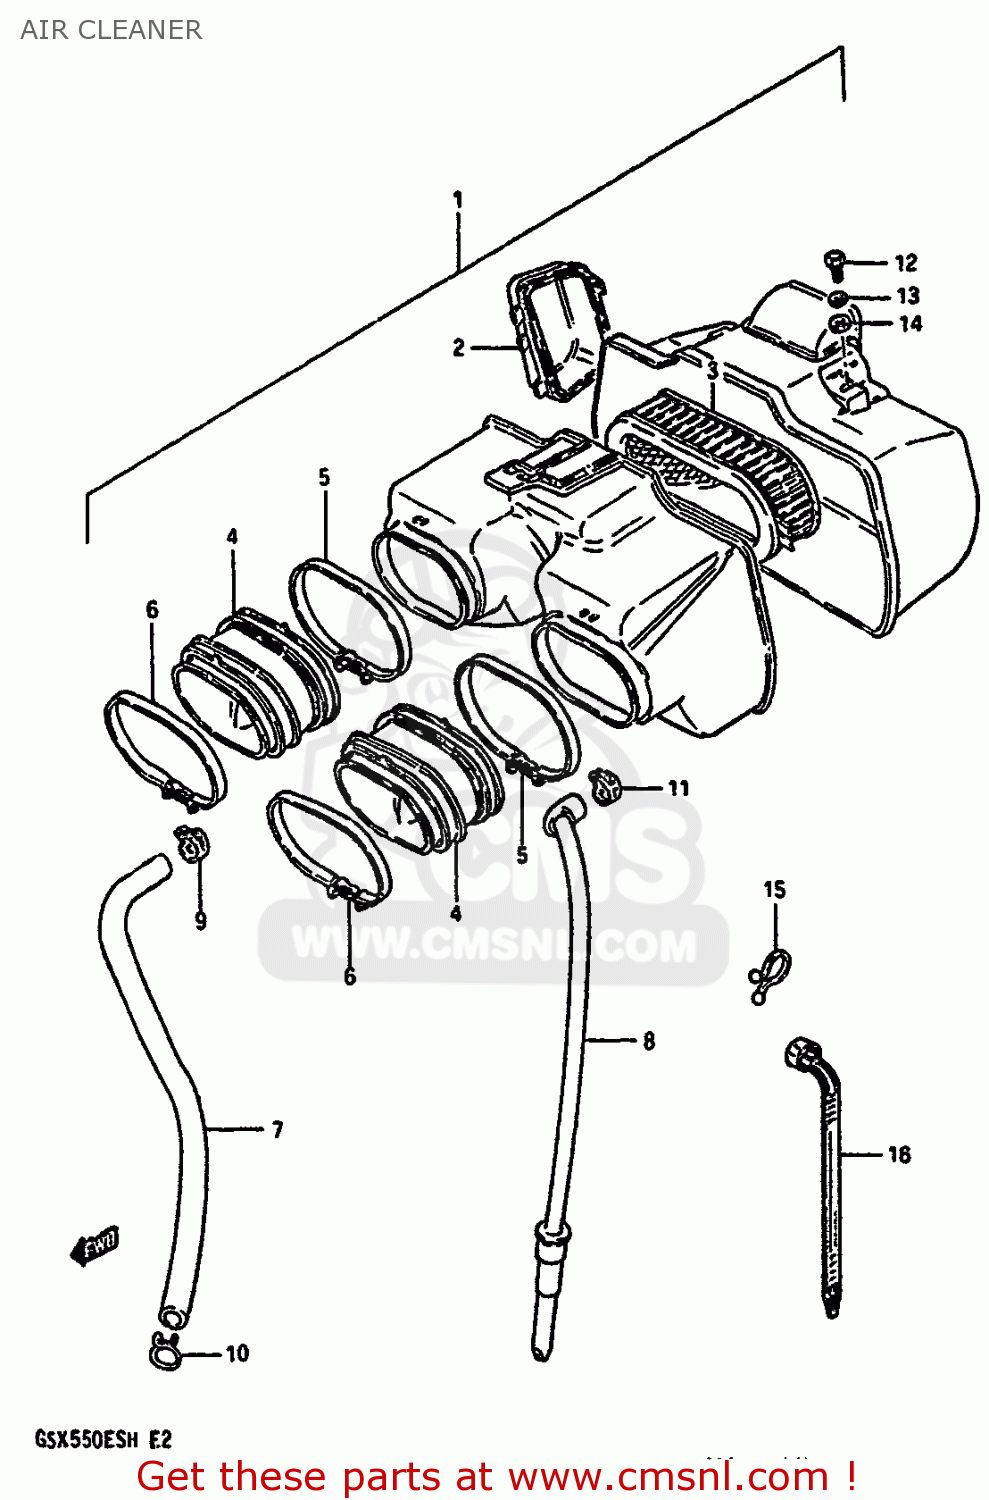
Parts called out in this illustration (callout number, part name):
1	CLEANER ASSEMBLY,AIR
2	CAP,AIR CLEANER
3	FILTER,AIR CLEANER
4	TUBE,AIR CLEANER OUTLET
5	CLAMP,AIR CLEANER
6	CLAMP,CARBURETOR SIDE
7	TUBE,BREATHER
8	DRAIN TUBE
9	CLIP
10	CLIP,BREATHER TUBE
11	CLIP
12	BOLT
13	WASHER,LOCK
14	WASHER
15	CLIP(ID:16)
16	CLAMP(L:165)
